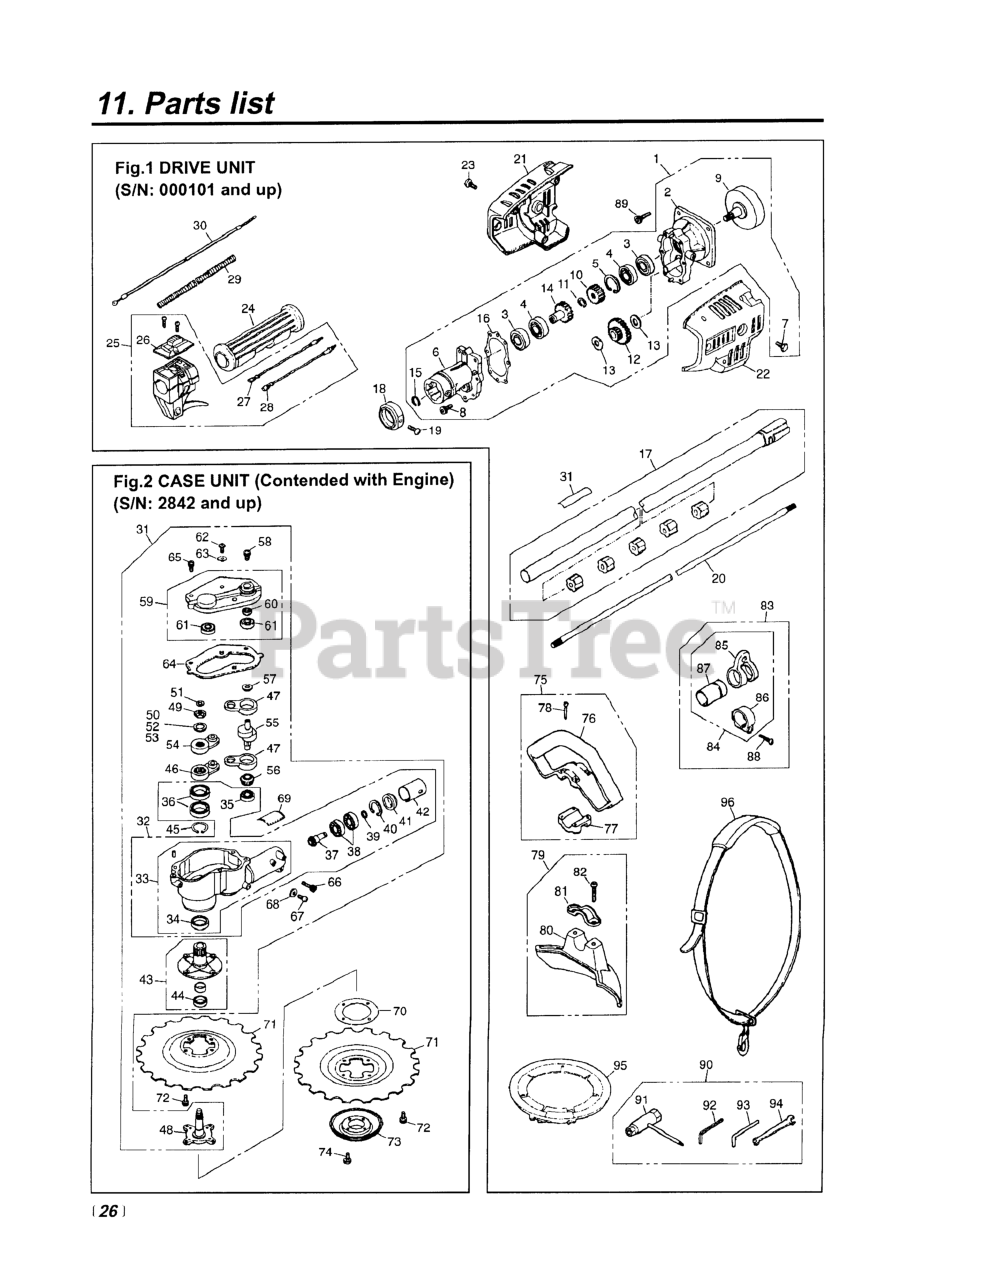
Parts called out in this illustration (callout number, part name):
1	MISSION ASSEMBLY
2	CASE, REAR COMP (RPLS -11101)
4	BEARING
5	RING, SNAP, M28 x 1.2
6	CASE, FRONT
7	BOLT, M6 x 8
8	BOLT, M5 X 20
9	DRUM
10	GEAR, PINION
11	RING, SNAP
12	GEAR (RPLS 3805-11330)
13	WASHER
14	GEAR, WHEEL
18	CAP
19	SCREW, M5 X 10
20	SHAFT
21	COVER, RIGHT (RPLS. -11510)
22	COVER, LEFT (RPLS -11520)
24	GRIP (RPLS 3577-32140 & 3220-
27	CORD (A), BLACK
28	CORD (B), RED
29	TUBE (RPLS 4900-72141)
30	CABLE (RPLS 5580-83100)
31	PLATE, NAME (SGCX2600S)
31	CUTTERCASE ASSEMBLY
32	CUTTERCASE (RPLS -98100)
34	SEAL, OIL
36	BEARING
37	PINION
38	BEARING (RPLS T3403-13510)
39	RING, SNAP
40	RING, SNAP, M26 X 1.2
41	PACKING
42	SPACER (RPLS -13950)
43	SHAFT, OUTER-C
44	SEAL, OIL
45	RING, SNAP, M20 x 1.2
46	ARM, LOWER (RPLS -13411)
48	SHAFT, INNER
50	SHIM, 0.3t
52	SHIM, 0.2T
53	SHIM, 0.1t
54	ARM, UPPER (RPLS -13611)
55	CRANKSHAFT (RPLS -13710)
56	GEAR
57	WASHER, M8 x 1.2
58	BOLT
59	COVER COMP
60	SEAL, OIL
62	SCREW, M6 x 10
63	WASHER, M6 x .8
64	GASKET
65	BOLT, M5 x 20
66	BOLT, M6 x 1.35
67	SCREW, M5 x 14
68	WASHER, M5x.8(RPLS 01624-20508
69	LABEL, CAUTION
72	BOLT, M6 x 8
73	STABILIZER (RPLS -15151)
74	SCREW, M5 X 8
75	HANDLE ASSEMBLY
76	HANDLE
78	SCREW, M5 x 35
79	GUARD ASSY (RPLS -24000)
80	GUARD (RPLS -24110)
81	CLAMP (REPLACES 5807-24120)
82	BOLT, M6 x 1.30
83	HANGER ASSEMBLY
84	HANGER COMPLETE
85	HANGER
86	CLAMP
87	SLEEVE
88	SCREW, M5 x 25
89	BOLT, M6 x 20
90	TOOL SET (SGCZ2500S)
91	SOCKET
92	WRENCH (TOOL)
93	WRENCH (TOOL)
94	SPANNER, 8 X 10 (RPLS 2540- )
95	COVER (REPLACES D0041) ACC.
